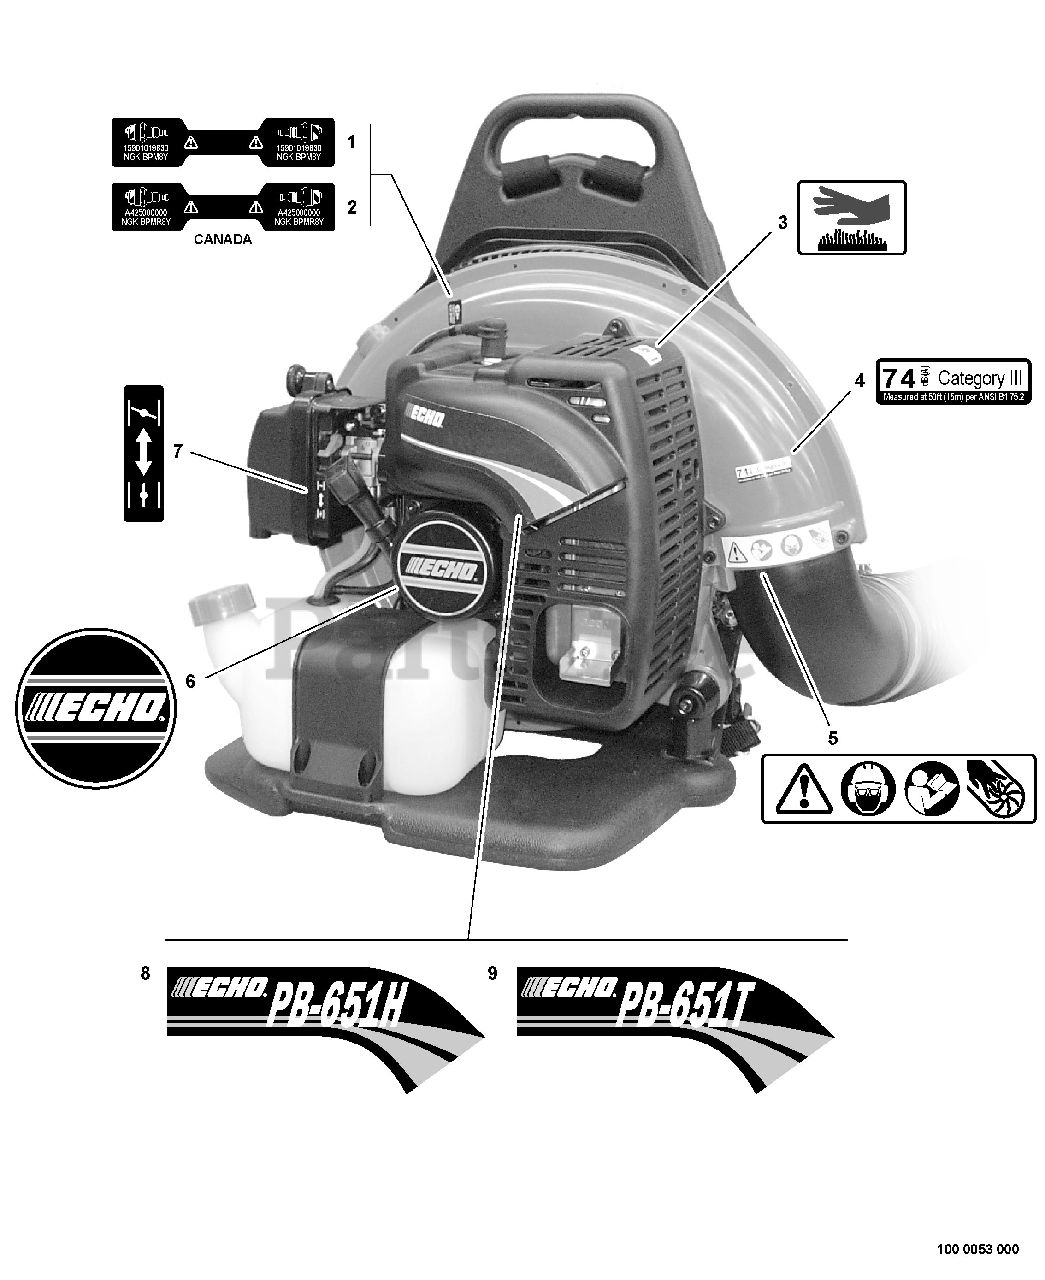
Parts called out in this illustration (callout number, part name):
1	LABEL - SPARK PLUG -- BPM-8Y
2	LABEL - SPARK PLUG -- BPMR-8Y
3	LABEL - HOT SURFACE
4	LABEL - NOISE 74dB(A) CAT III
5	LABEL - CAUTION
6	LABEL - ECHO
7	LABEL - CHOKE
8	LABEL - MODEL PB-651H
9	LABEL - MODEL PB-651T
